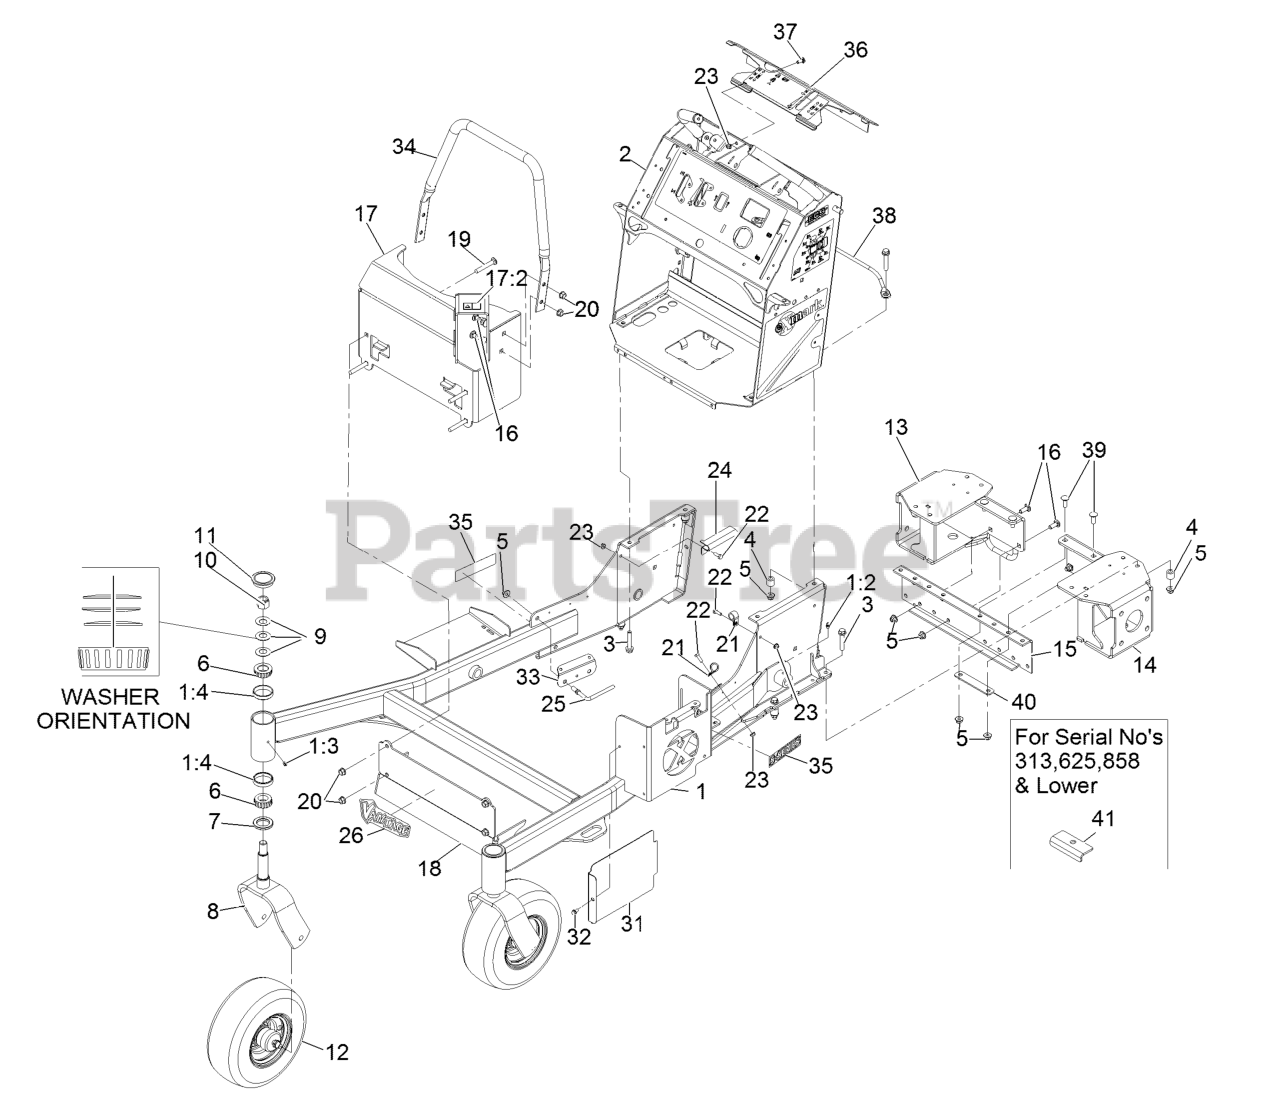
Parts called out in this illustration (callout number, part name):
1	FRONT FRAME ASM
1:2	FITTING-GREASE
1:4	CUP-BEARING
2	TOWER ASSEMBLY
3	SCREW-HHF
5	NUT-HF, NI
6	Cone-Bearing Tapered Roller
7	SEAL-GREASE
8	FORK-CASTER
9	WASHER-BELLVILLE
10	NUT-LOCK, NI
11	CAP-GREASE
12	WHEEL/TIRE AND BEARING AS
13	RH MOTOR MOUNT ASM
14	LH MOTOR MOUNT ASM
15	MOUNT-MOTOR, CENTER
16	SCREW-CARR
17:2	DECAL-WARNING
18	PANEL-GUARD
19	SCREW-CARR
21	CLAMP-CABLE
22	SCREW-HH
24	BRACKET-HOSE, FUEL (DOUBL
25	GUIDE-HOSE, SUPPORT
26	DECAL-VANTAGE LOGO
31	SHIELD-HEAT, TALL
32	SCREW-HWH
33	GUARD-HOSE
34	TUBE-GUARD
35	DECAL-X-SERIES
36	CONTROL PANEL W/DECALS
37	BOLT-CARR
38	ROD, GUARD
39	Bolt-Carriage 3/8-16 X 1 1/4
40	SPACER, UP STOP
41	Spacer-Up Stop
